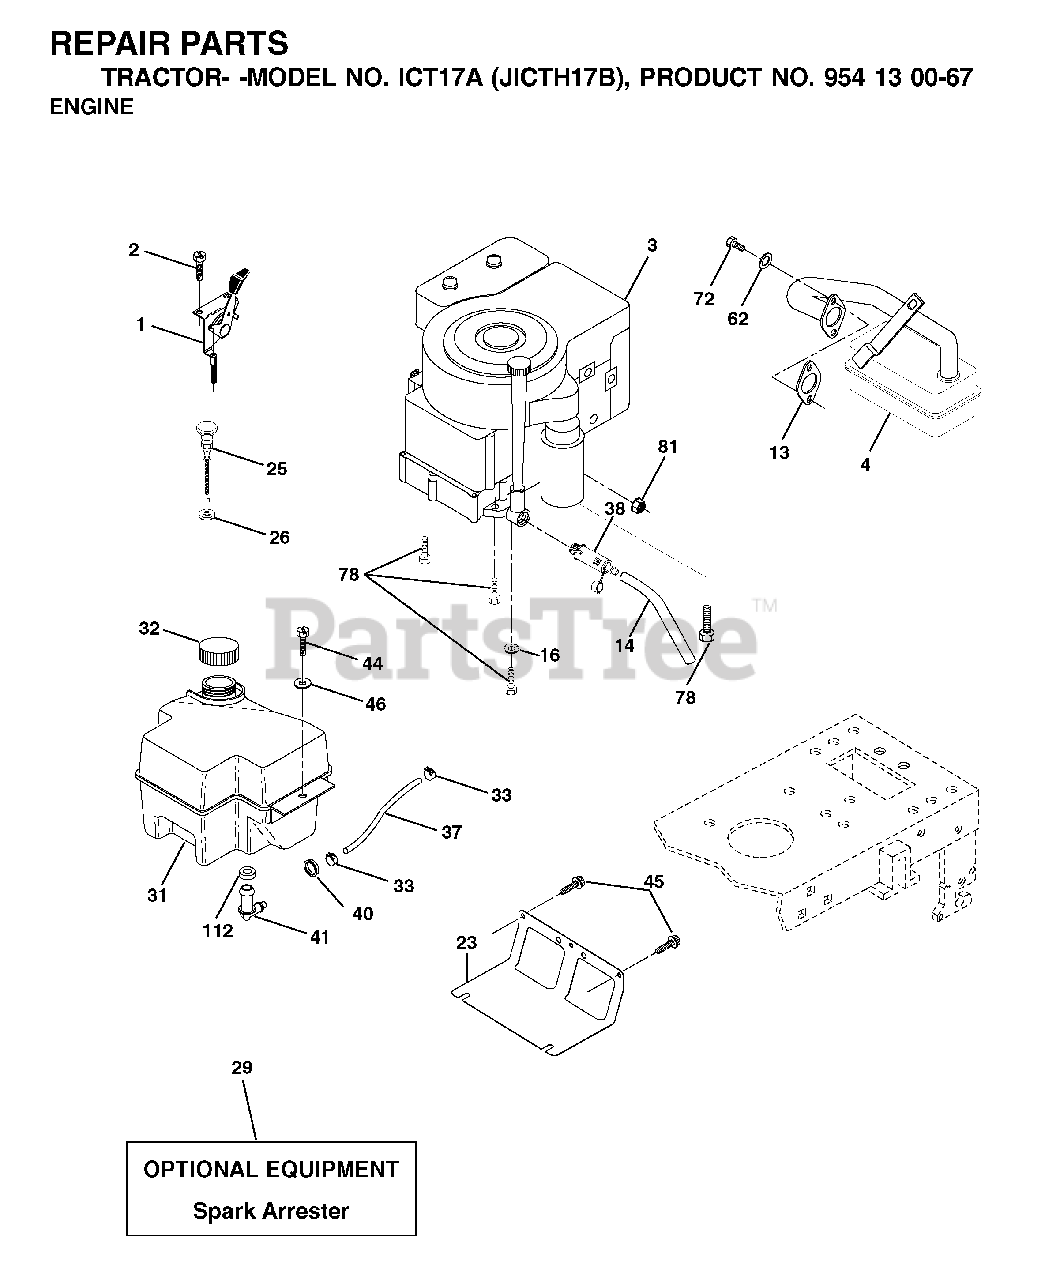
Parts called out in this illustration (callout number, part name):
1	CONTROL TH/CH FLAG
2	SCREW
13	REPL BY 532 27 22-93
14	TUBE, DRAIN OIL ASM.
16	LOCKWASHER
23	SHEILD.BROWNING.DBR.GUARD
26	NUT KEPS 3/8 - 24 UNF
29	ARRESTER SPARK (OPTIONAL)
31	GAS TANK 2GAL
32	FUEL CAP
33	HOSE CLAMP
37	LINE.FUEL.20
38	PLUG, OIL DRAIN EASY
40	GROMMET T
41	STEM FUEL TANK
44	SCREW HEXWSHR 1/4-20X3/4
45	SCREW, 3/8-16X3/4
62	LOCKWASHER
72	SCREW
78	SCREW.3/8-16
81	NUT
112	BUSHING OUTLET T
